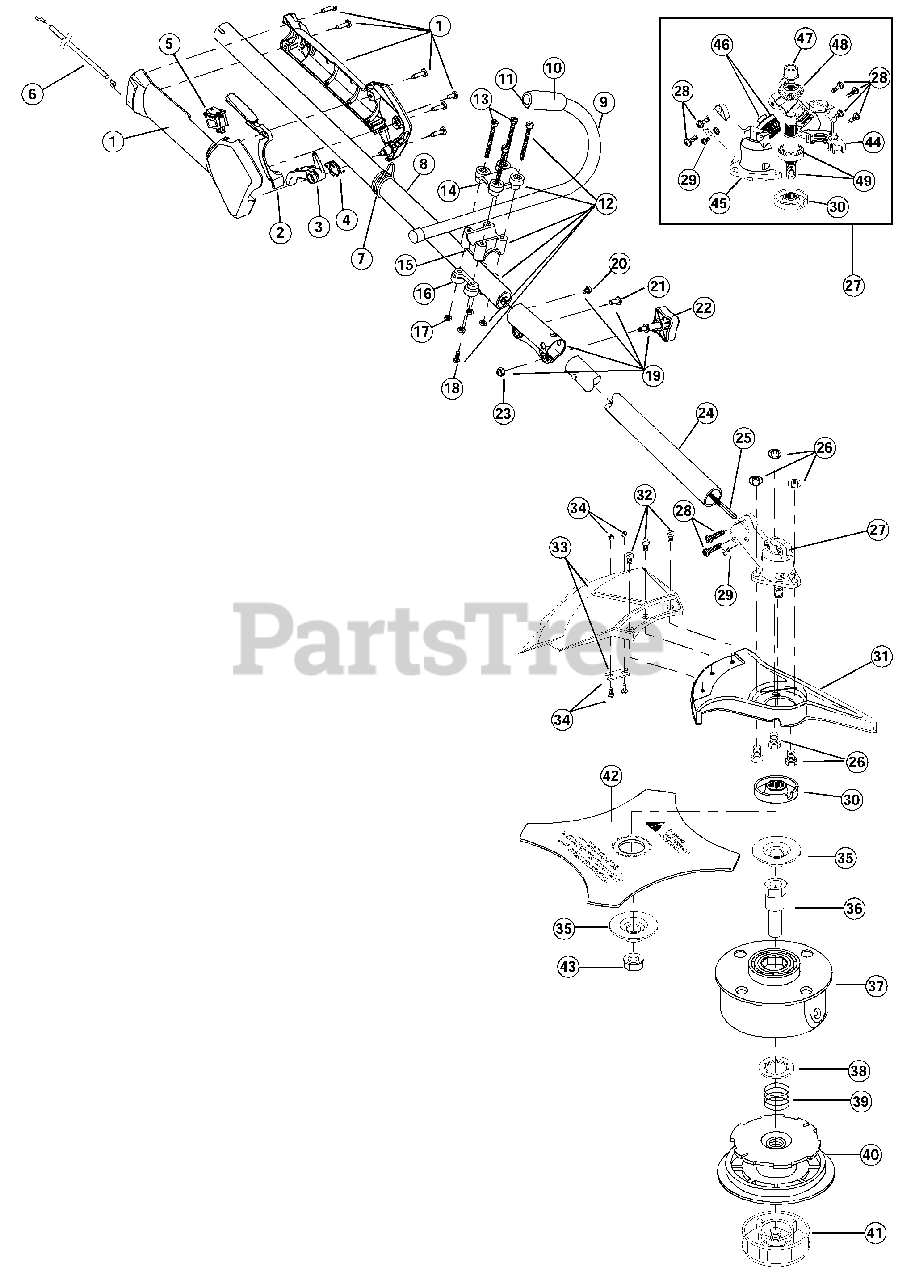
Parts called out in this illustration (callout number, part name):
1	Throttle Housing and Trigger Assembly
2	Throttle Trigger Lock-Out
3	Throttle Trigger
4	Throttle Trigger Spring
5	Switch Assembly
6	Throttle Cable Assembly
7	Harness Clip
8	Upper Drive Shaft Housing Assembly
9	J-Handle Assembly
11	Tube Closure
12	Handle Bracket Assembly
14	Upper Handle Clamp
15	Middle Handle Clamp
16	Lower Handle Clamp
18	Anti-Rotation Screw
19	Click-Link Coupler
22	Adjustment Knob
23	Knob Retaining Nut
24	Lower Drive Shaft Housing Assembly
25	Lower Flexible Drive Shaft
26	Shield Mount Screw Assembly
27	2 piece Gearbox Assembly
28	Gearbox Mounting Hardware
29	Anti-Rotation Screw
30	Blade Driver
31	Blade Shield/Shield Mount
32	Shield Mounting Screw
33	Shield and Blade Assembly
34	Blade Assembly
35	Retaining Washer
36	Spool Shaft
37	Outer Spool and Eyelet Assembly
38	Retainer
39	Spring
40	Inner Reel
41	Bump Head Knob Assembly
42	4-Tooth Blade
43	Nut
44	Left Housing
45	Right Housing
46	Pinion Gear Assembly
47	Output Shaft Bushing
48	Output Shaft Gear
49	Output Shaft Assembly
